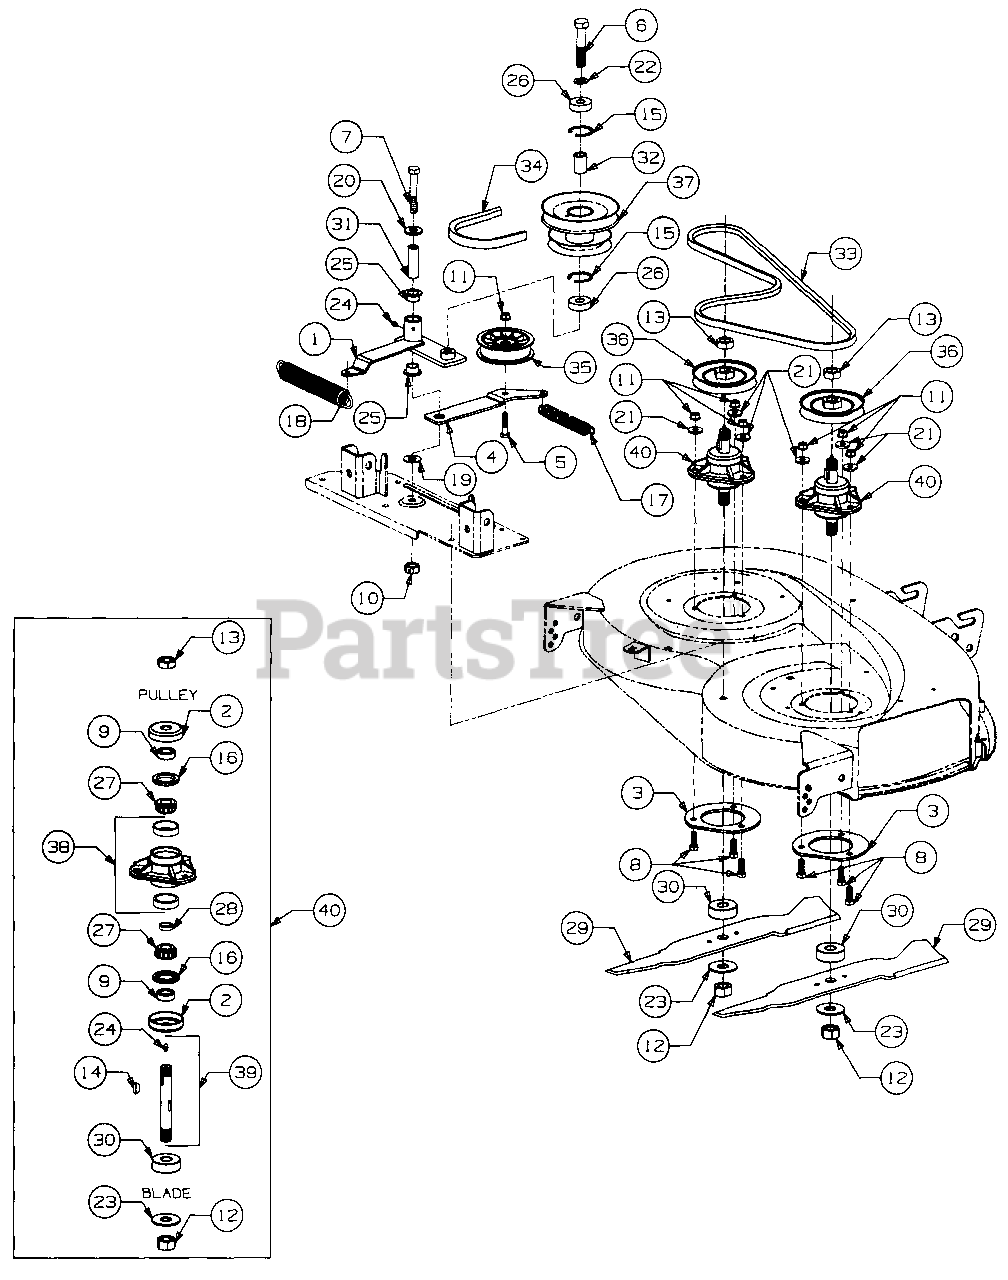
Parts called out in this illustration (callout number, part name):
2	Cup, Spindle Hdn
3	Plate, Spindle Mtg
5	Screw, Hex Cap, 3/8-16 x 1.50 Lg GR5
6	Screw, Hex Cap, 5/8-18 x 13.0 Lg GR5
7	Screw, Hex Cap, 1/2-20 x 13.0 Lg GR8
8	Screw, Hex Cap, 3/8-16 x 1.25 Lg GR5
9	Spacer, .755 x 1.25 x .44 Lg
10	Nut, Hex Center Lock, 1/2-20
11	Nut, Hex Flanged Lock, 3/8-16
12	Nut, Hex, 3/4-16 GR8
13	Nut, Hex Jam, 3/4-16 GR5
14	Key, #91 Woodruff, 1/4 x 3/4 Hdn
15	Snap Ring, Internal
16	Seal, Oil, 1.25 x 1.874 x .25
17	Spring Extension, .88 OD x 6.12 Lg
18	Spring, Extension, 1.25 OD x 8.15
19	Washer, Flat, .531 x 1.25 x .036 Thk
20	Washer, Flat, .531 x 1.25 x .100 Thk
21	Washer, Flat, .385 x 1.0 x 6.135 Thk
22	Washer, Flat, .63 x 1.0 x .063 Thk Hdn
23	Washer, Flat, .781 x 2.0 x .105 Thk
24	Fitting, 3/16 Drive Lube
25	Bearing, Flange, 3/4 ID x .53 Lg
26	Bearing, Ball, .62 ID x 1.57 OD x .44 Thk
27	Cone, Bearing
28	Spacer, Bearing
29	Blade, Low Lift, 19.38 Lg
30	Spacer
31	Spacer, Idler Brkt, .50 ID x .75 OD x 2.25 Lg
32	Spacer, Pulley, .635 ID x .88 OD x 1.25 Lg
33	Belt, Spindle, A-Section x 59 Lg
34	Belt, PTO, B-Section x 112.4 Lg
35	Pulley, Flat Idler, 3.5 OD
36	V-Pulley, 4.62 OD
37	Pulley, Double
38	Housing w/Cups, Spindle
39	Kit, Shaft w/Seal
40	Spindle Assy, Blade
